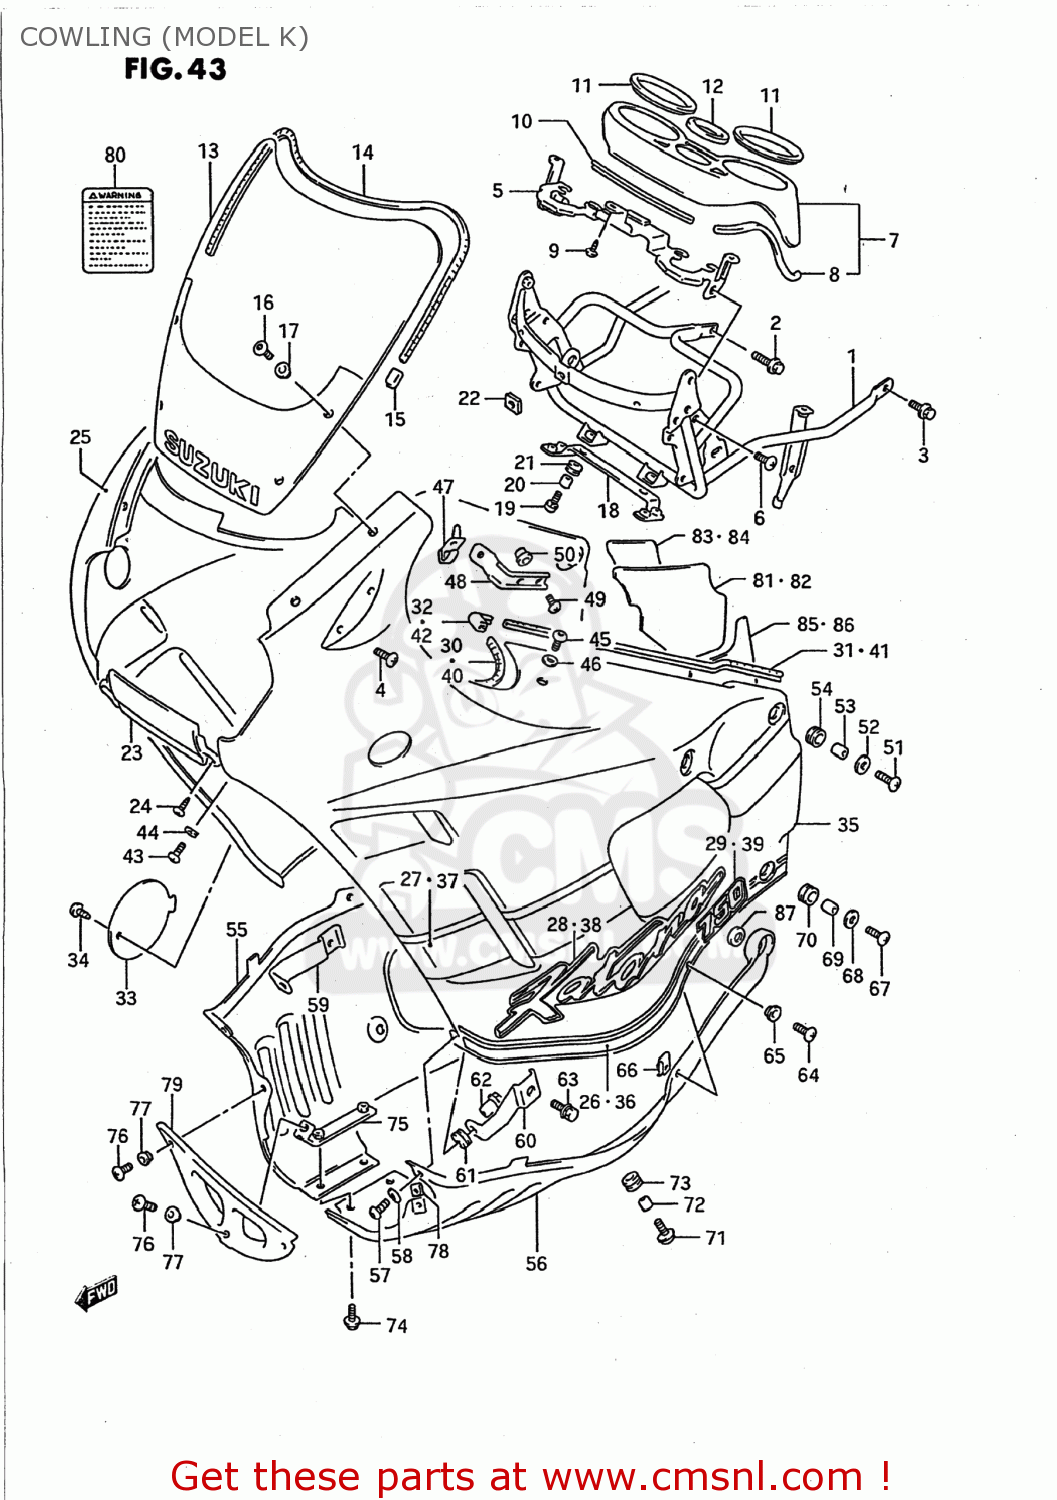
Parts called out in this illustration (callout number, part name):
1	BRACE,COWLING
2	BOLT
3	BOLT 6X12
4	SCREW 6X12
5	PLATE,METER FITING
6	SCREW 6X12
7	COVER COMP,METER
8	MOLDING
9	SCREW 5X8
10	11
11	CUSHION,SPEEDOMETER
12	CUSHION,FUEL METER
13	WINDOW,COWLING
14	MOLDING
15	CAP,MOLDING END
16	SCREW
17	WASHER(5.2X11X1)
18	PLATE,COWL CTR PANEL
19	SCREW(6X20)
20	SPACER (6,8X10X9.4)
21	CUSHION
22	CUSHION,SCREEN
23	PANEL,COWLING,CENTER
24	SCREW
25	COVER ASSEMBLY,COWLING,RIGHT (R
26	TAPE,COWLING SIDE STRIPE
27	TAPE,COWL SIDE,R
28	EMBLEM,COWLING SIDE (KATANA)
29	EMBLEM,COWLING SIDE (7)
29A	COVER,COWLING METER,SIDE
29B	COVER,COWLING METER,SIDE
29C	29-1
30	MOLDING
31	MOLDING
32	JOINT,MOLDING END
33	LID,OIL
34	SCREW(6X16)
35	COVER ASSEMBLY,COWLING,LEFT
36	TAPE,COWLING SIDE STRIPE
37	TAPE,COWLING SIDE,LEFT
38	EMBLEM,COWLING SIDE (KATANA)
39	EMBLEM,COWLING SIDE (7)
39A	COVER,COWLING METER,SIDE
39B	COVER,COWLING METER,SIDE
39C	39-1
40	MOLDING
41	MOLDING
42	JOINT,MOLDING END
43	SCREW(6X25)
44	WASHER(6.5X18X1.5)
45	SCREW(6X16)
46	WASHER(6.3X16X1.5)
47	BRACKET,COWLING UPR,R
48	BRACKET,COWLING UPR,L
49	SCREW(6X25)
50	NUT,COWLING SIDE BRKT
51	SCREW(6X25)
52	WASHER(6.5X18X1.5)
53	SPACER (6.1X9X9)
54	CUSHION
55	COVER,COWLING UNDER,R
56	COVER,COWLING UNDER,L
57	SCREW(6X30)
58	WASHER(6.5X18X1.5)
59	BRACKET,COWLING LWR,R
60	BRACKET,COWLING LWR,L
61	CUSHION
62	NUT,COWLING,FR
63	BOLT
64	SCREW(5X14)
65	WASHER(5.2X14X1.5)
66	NUT,HEADLAMP HOUSING,UPPER
67	SCREW(6X25)
68	WASHER(6.5X18X1.5)
69	SPACER(6.1X8X14.5)
70	CUSHION
71	SCREW(6X20)
72	SPACER (6.1X9X9)
73	CUSHION
74	75
75	BRACKET,FR UNDER COWL
76	SCREW
77	WASHER(5.2X14X1.5)
78	NUT,HEADLAMP HOUSING,UPPER
79	COVER,COWLING,UNDER,FRONT
80	LABEL (WARNING SCREEN)
81	BALANCER SHEET,COWLING,R
82	BALANCER SHEET,COWLING,L
83	CUSHION,COWLING,R
84	CUSHION,COWLING,L
85	SHEET,COWLING BALANCER,R
86	SHEET,COWLING BALANCER
